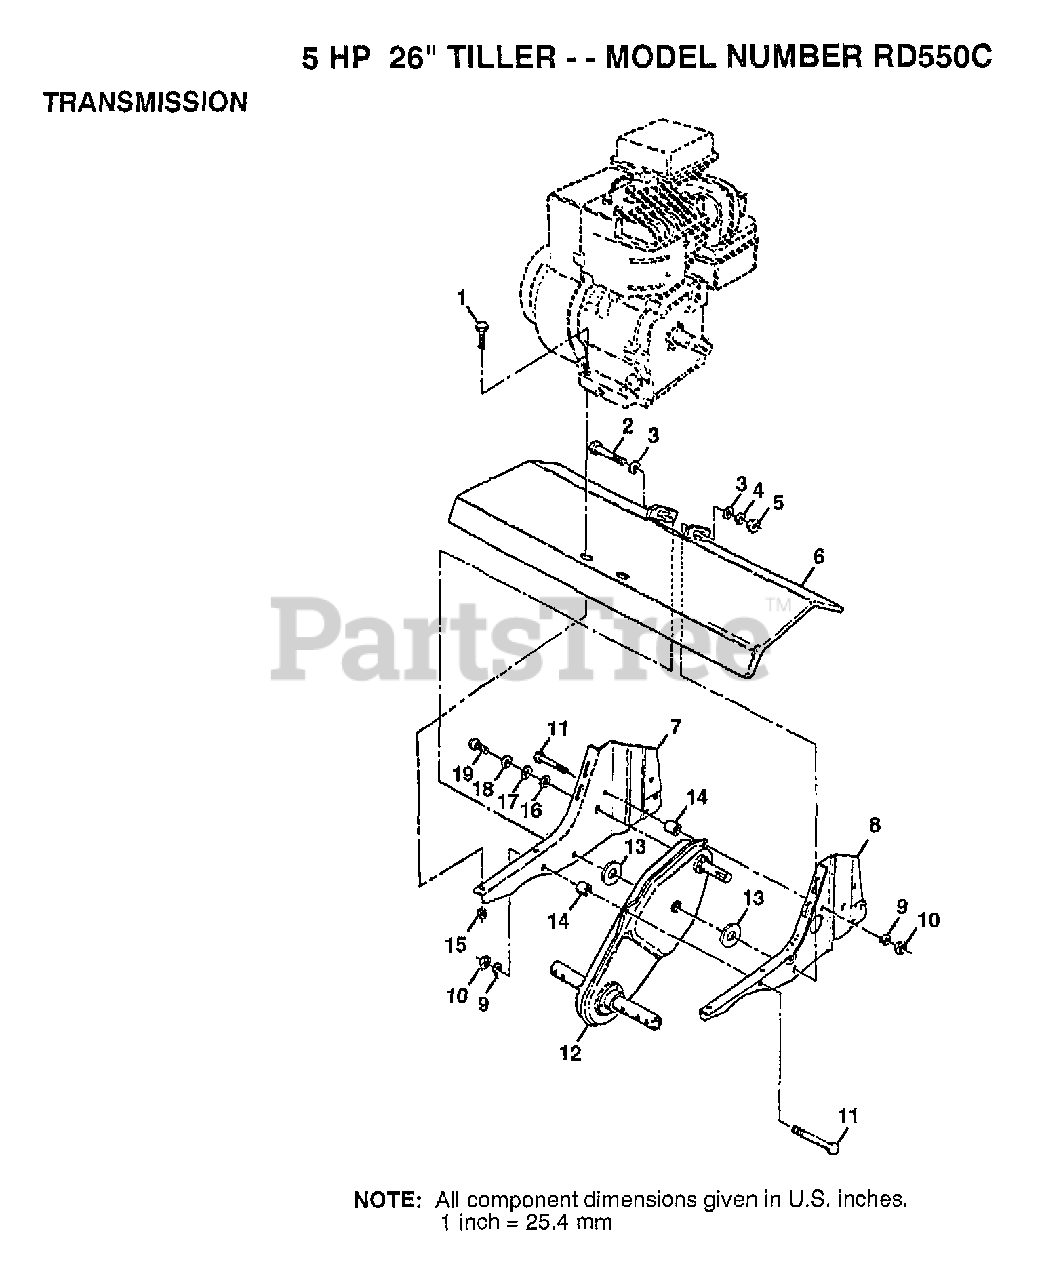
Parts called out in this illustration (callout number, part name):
1	BOLT.HEX.5/16-1.5
2	BOLT.3/8-24X3.75
3	WASHER
4	LOCKWASHER
5	GRIPCO NUT
8	BRACKET.ENG.LH.
9	LOCKWASHER
10	NUT.HEX.5/16-18
14	SPLIT SPACER RT
16	WASHER
17	WASHER
18	LOCKWASHER
19	BOLT
